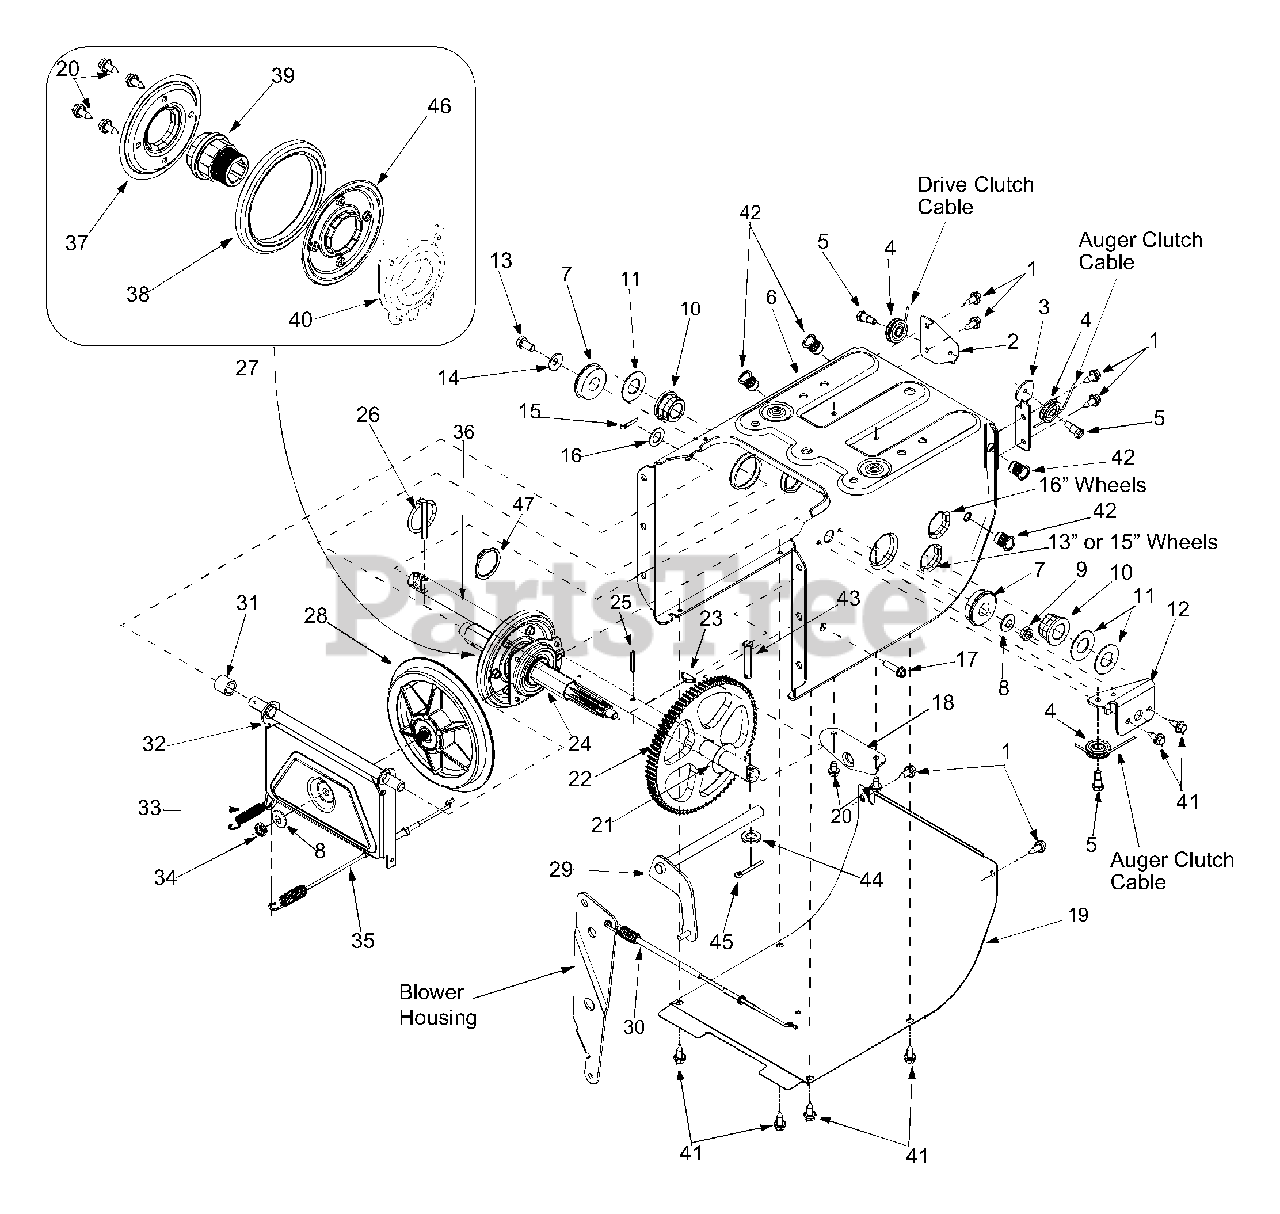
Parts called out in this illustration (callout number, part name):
1	?Hex Screw
5	Hex Screw 1/4-28
6	Frame Assembly
7	Ball Bearing
8	Bell Washer
9	Lock Jam Nut
10	Hex Flange Bearing
11	Flat Washer
14	Bell Washer.340 ID x.872 OD
15	?Cotter Pin
16	Flat Washer.536 ID x.930 OD
17	Hex Washer Screw 1/4-20
21	Flat Washer.760 ID x.50 OD
24	7-Tooth Shaft
25	Roll Pin
26	Klik Pin
27	Friction Wheel Assembly
28	Friction Disc Wheel
29	Wheel Shift Rod Assembly
30	?Drive Cable
31	Spacer
34	Jam Nut 3/8-24
35	Drive Cable
36	Axle 13" Wheels
36	Axle 16" Wheels
37	Friction Plate
38	Friction Wheel Rubber
39	Friction Wheel Hub
40	Friction Wheel Bearing
41	Tap Screw 1/4-20
42	Insert Nut 5/16-18
43	Clevis Pin
44	Flat Washer.281 ID x.50 OD
45	Cotter Pin
46	Friction Plate
47	Snap Ring
